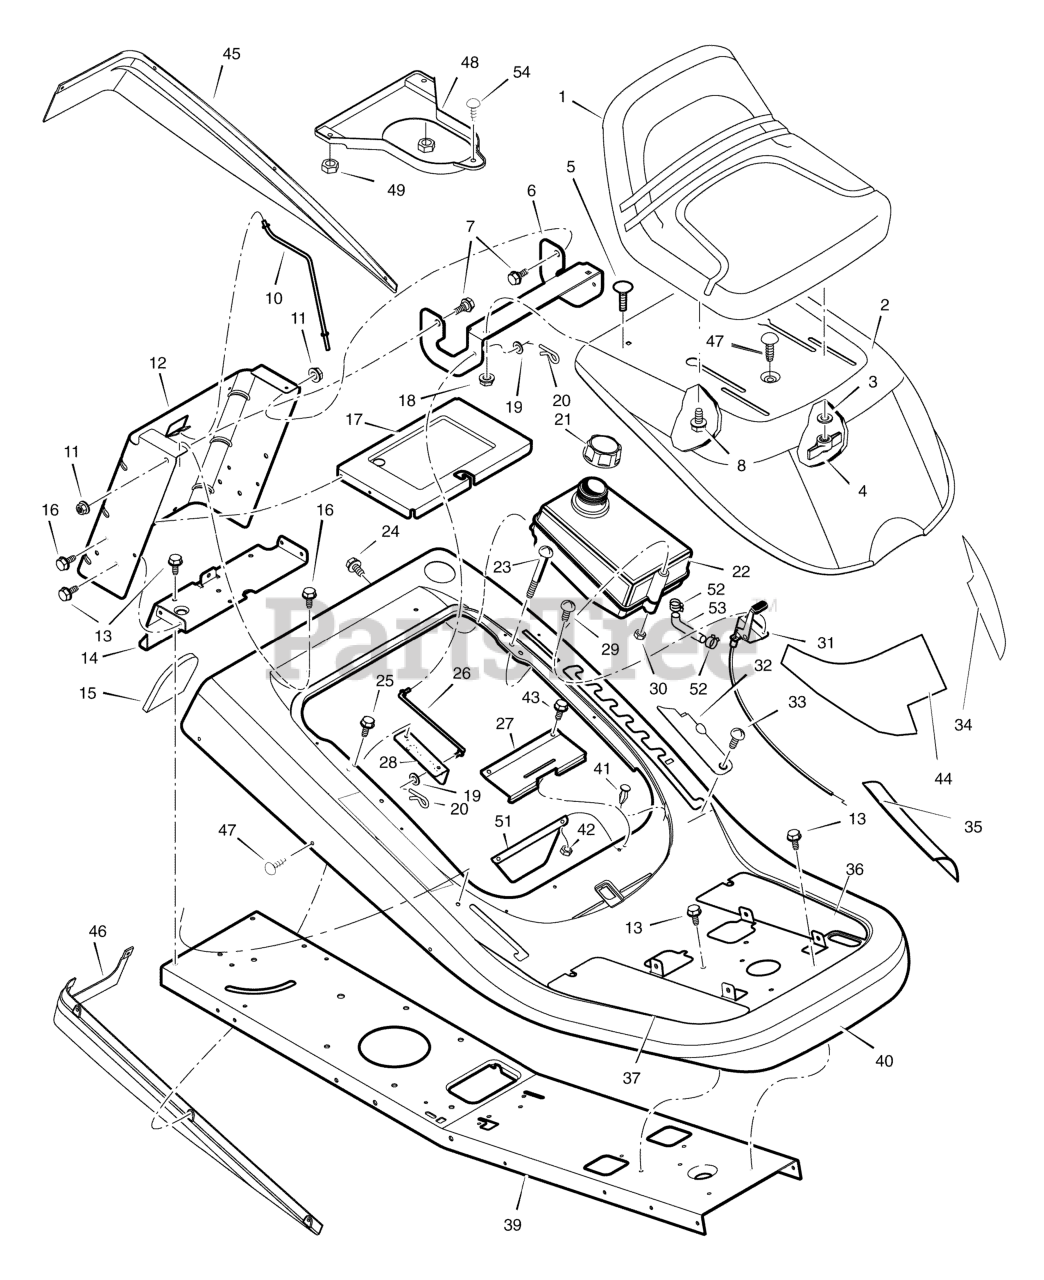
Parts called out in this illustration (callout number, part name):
1	SEAT
3	WASHER
4	BOLT, Wing
5	BOLT, Carriage
6	BRACKET, Hinge
7	BOLT, Shoulder
8	BOLT, Shoulder
10	ROD, Battery
11	NUT, Flange
12	PLATE, Rear
14	PLATE, Hitch
17	TRAY, Battery
18	NUT, Flange
20	PIN, Cotter
21	CAP, Fuel Tank
22	TANK, Fuel
26	ROD, Hood Prop
27	SPRING, Seat Deck
28	BRACKET, Prop Rod
30	NUT, Nylock
31	CONTROL, Throttle
32	COVER, Detent
33	BOLT, Shoulder
34	HEAT SHIELD, Hood L.H.
35	HEAT SHIELD, Hood Upper
36	FOOTMAT, Left
37	FOOTMAT, Right
39	FRAME
42	NUT
43	SCREW
44	HEAT SHIELD, Hood R.H.
45	TRIM, Left
46	TRIM, Right (Gray)
49	NUT, Hex 5/16--18
51	HEAT SHIELD
52	CLAMP, Hose
53	LINE, Fuel
54	FASTENER, Panel
